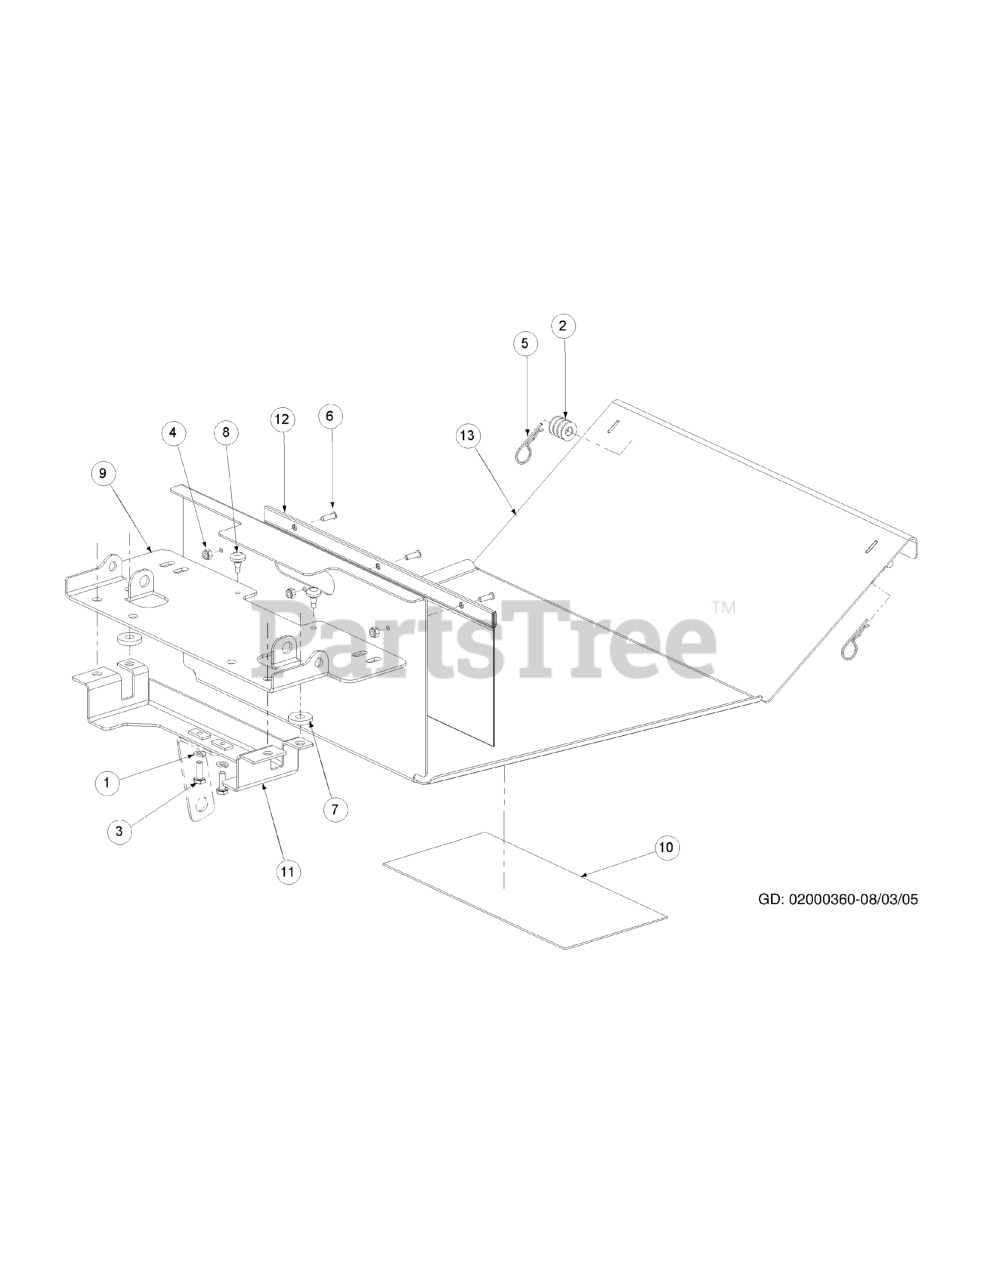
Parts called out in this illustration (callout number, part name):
1	Lock Washer, 1/4
3	Hex Cap Screw, 1/4-20, .75
4	Lock Nut, Nylon Insert, 10-32
5	Hair Pin, 3/8-1/2
6	Screw, Phillips Head, Machine, 10-32 x 5/8
7	Washer
8	Rubber Bumper, .62 OD x .22 Thick
10	Label, Belt Routing and Lubrication
11	Support, Seat Bracket
12	Bag, Debris Storage
13	Floor Panel Assembly
